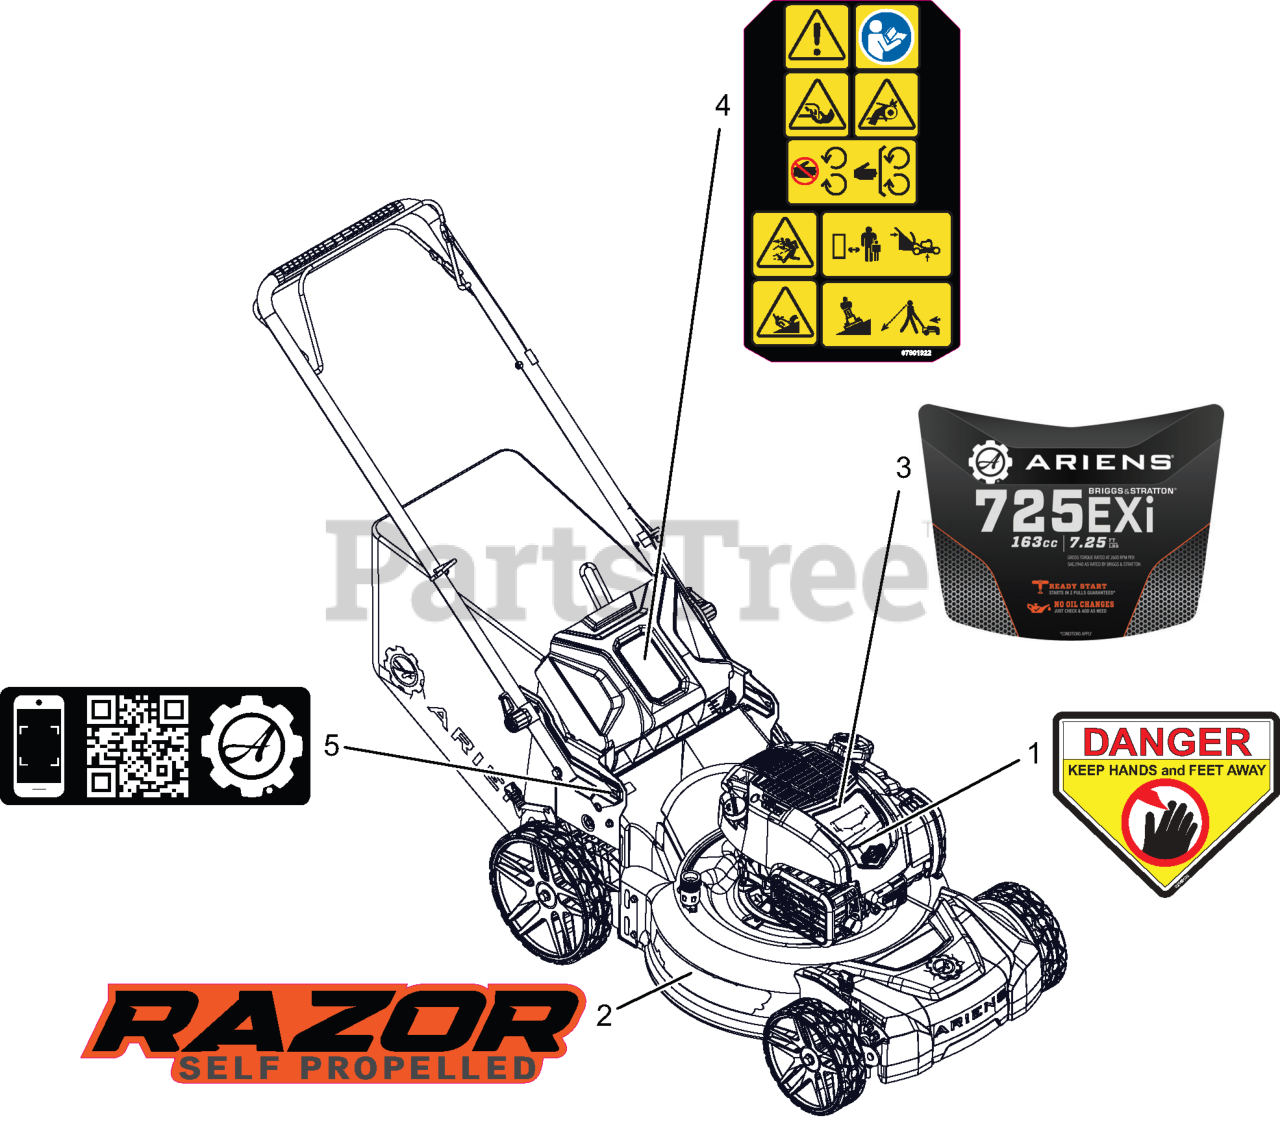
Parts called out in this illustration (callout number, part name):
1	DECAL, DANGER
2	DECAL, ARIENS SP
3	DECAL, ENGINE 163CC
4	DECAL, MAIN SAFETY - WALK
5	DECAL, RAZOR QR
